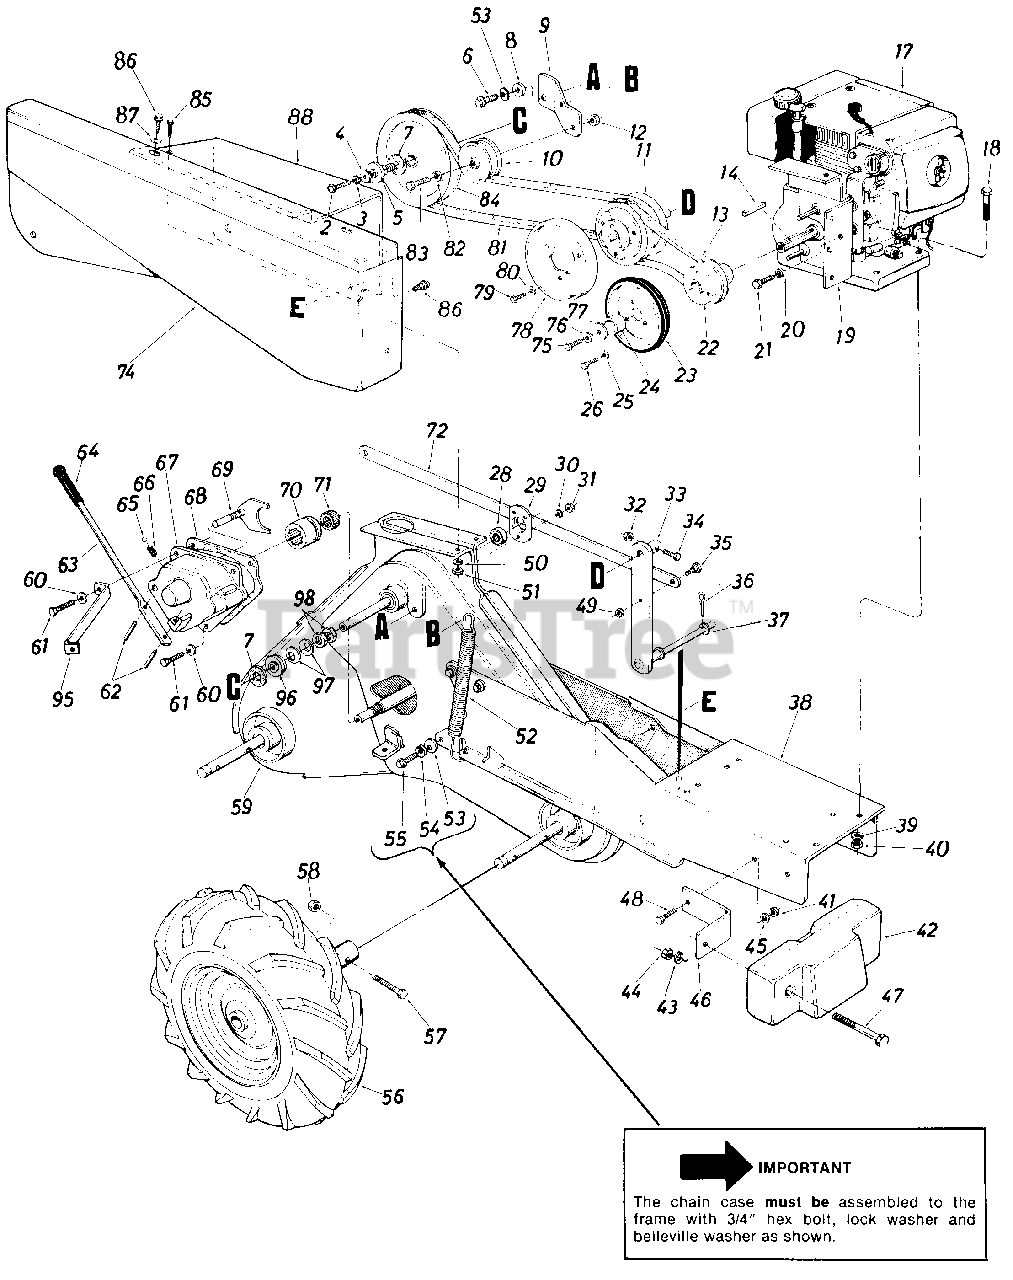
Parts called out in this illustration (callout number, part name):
2	Hex L-Bolt 5/16-24 x 1.5" Lg.
3	L-Wash. 5/16" I.D.
4	Fl-Wash. 5/16" I.D. x 1.125"O.D.
5	Friction Disc Ass'y.
6	Hex Bolt 3/8-24 x 1.25" Lg.
7	Friction Pad
8	Shoulder Spacer
9	Idler Bracket
10	Fl-Idler 2.75" Dia.
11	Variable Speed Ass'y.
12	Hex Ins. L-Nut 3/8-16 Thd.
13	"V"-Belt 5/8" x 27.0" Lg.
14	Sq. Key 1/4" x 2.00" Lg.
17	Engine
18	Hex Bolt 5/16-18 x 1.75" Lg.
19	Belt Cover Support Ass'y.
20	Internal L-Wash. 1/2" I.D.
21	Hex Bolt 1/2-20 x .75" Lg.
22	Engine Pulley Ass'y.
23	Friction Wheel Ass'y.
24	Spacer
25	L-Wash. 5/16" I.D.*
26	Hex Bolt 5/16-18 x .50" Lg.
28	Ball Bearing
29	Bearing Housing 1-3/8" O.D.
30	L-Wash. 1/4" I.D.
31	Hex Nut 1/4-28 Thd.
32	Hex Ins. L-Nut 1/4-20 Thd.
33	Variable Speed Brkt. Ass'y.
34	Hex Bolt 1/4-20 x 1.25" Lg.
35	Shld. Bolt 1/2" Dia. x .25" Lg.
36	Cotter Pin 118" Dia. x 1.0" Lg .
37	Fl-Wash. .686" I.D. x 1.25" O.D.
38	Frame Ass'y.
39	L-Wash. 5/16" I.D.
40	Hex Nut 5/16-18 Thd.
41	Hex Cent. L-Nut 3/8-24 Thd.
42	Weight
43	Fl-Wash. .50" I.D. x 1.0" O.D.
44	Hex Nut 1/2-13 Thd.
45	L-Wash. 3/8" I.D.
46	Weight Mtg. Brkt.
47	Hex Bolt 1/2-13 x 4.50" Lg.
48	Hex Bolt 3/8-24 x 1.00" Lg.
49	Hex Ins. L-Nut 3/8-16 Thd.
50	L-Wash. 1/4" I.D.
51	Hex Cent. L-Nut 1/4-28 Thd.
52	Spring Idler Bracket
53	Belleville Wash. 3/8" I.D.
54	L-Wash. 3/8" I.D.
55	Hex Self-Tap Scr. 3/8-16 x .75" Lg.
56	Wheel Ass'y. Comp.-R.H.
57	Hex Bolt 3/8-24 x 1.25" Lg.*
58	Hex Ins. L-Nut 3/8-24 Thd.
59	Chain Case Ass'y. Comp.
60	L-Wash. 5/16" I.D.
61	Hex Tap Tite Scr. 5/16-18 x .75" Lg.
62	Headed Spiral Pin 3/16 x 13/16" Lg.
63	Engagement Lever
64	G ri p
65	Ball Detent.250" Dia.
66	Compression Spring
67	Shift Housing-R.H.
68	Gasket-Shift Housing
69	Shift Yoke Ass'y.-R.H.
70	Clutch Dog
71	Clutch Dog Driver
72	Control Brkt.
74	Shroud Belt Cover
75	Hex Bolt 7/16-20 x 2.25" Lg.
76	L-Wash. 7/16" I.D.
77	Fl-Wash. .44 I.D. x 1.38" O.D.
78	Friction Disc
79	Hex Bolt 1/4-28 x .50" Lg.
80	L-Wash. 1/4" I.D.
81	"V"-Belt 5/8" x 51" Lg.
82	L-Wash. 3/8" I.D.
83	Hex Bolt 3/8" x 1.50" Lg.
84	Input Pulley-Chain Case
85	Hex Bolt 1/4-28 x .62" Lg.
86	Hex Wash. Hd. Self-Tap Scr.
87	Fl-Wash. 1/4" I.D.
88	Belt Cover Shroud
95	Brace
96	Floating Disc
97	Spring Bell-Wash.
98	Hex Jam Nut 1.0-14
